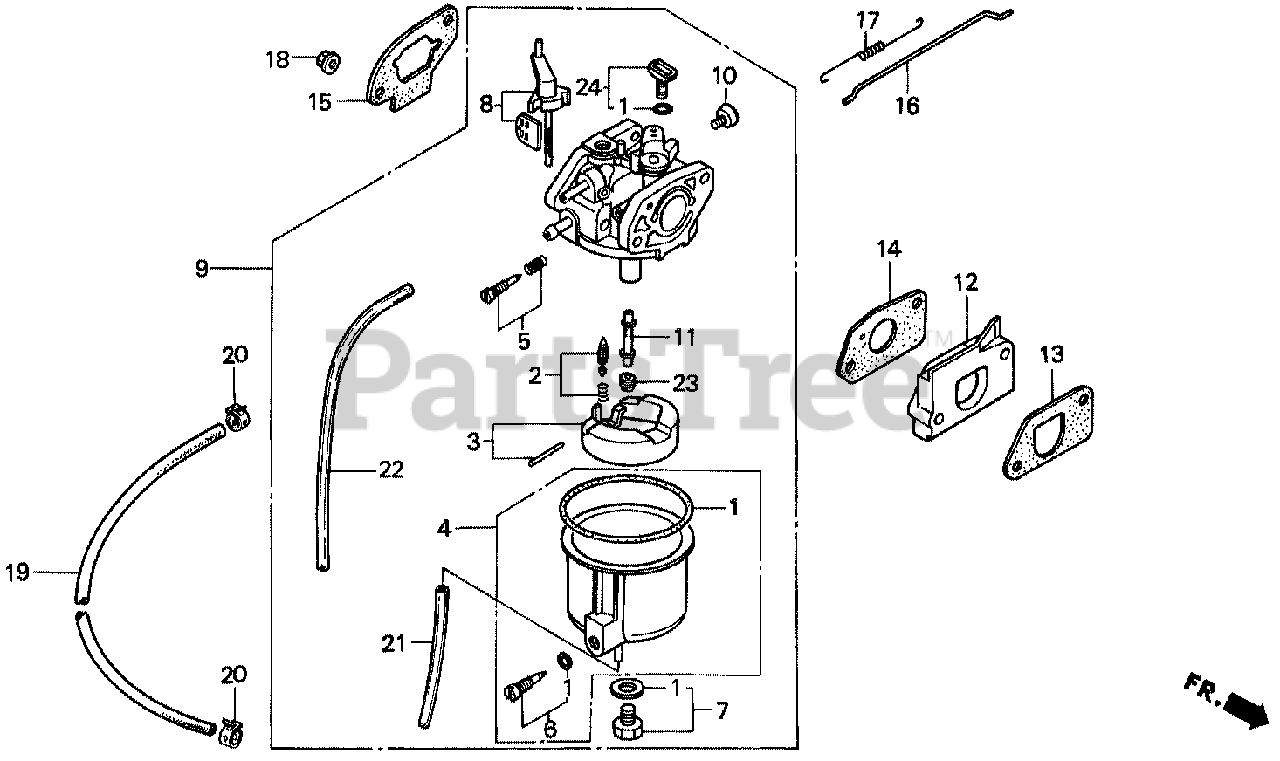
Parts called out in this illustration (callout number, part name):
1	GASKET SET
2	VALVE SET, FLOAT
4	CHAMBER SET, FLOAT
5	SCREW SET, PILOT
6	SCREW SET, DRAIN
9	CARBURETOR ASSY. (BF03A A)
9	CARBURETOR ASSY. (BF03A B/C)
10	SCREW, THROTTLE STOP
11	NOZZLE, MAIN
12	INSULATOR, CARBURETOR
13	GASKET, INSULATOR
14	GASKET, CARBURETOR
15	GASKET, AIR CLEANER
16	ROD, GOVERNOR
17	SPRING, THROTTLE RETURN
18	NUT, FLANGE (5MM)
19	BULK HOSE, FUEL (4.5X3000) (4.5X470)
20	CLAMP, TUBE (D8.5)
21	BULK HOSE, VINYL (3.5X6.5X8000) (3.5X6.5X160)
22	BULK HOSE, VINYL (3.5X6.5X8000) (3.5X6.5X250)
23	JET, MAIN (#50)
23	JET, MAIN (#52)
23	JET, MAIN (#55)
23	JET, MAIN (#58)
23	JET, MAIN (#60)
24	JET SET, PILOT (#35)
